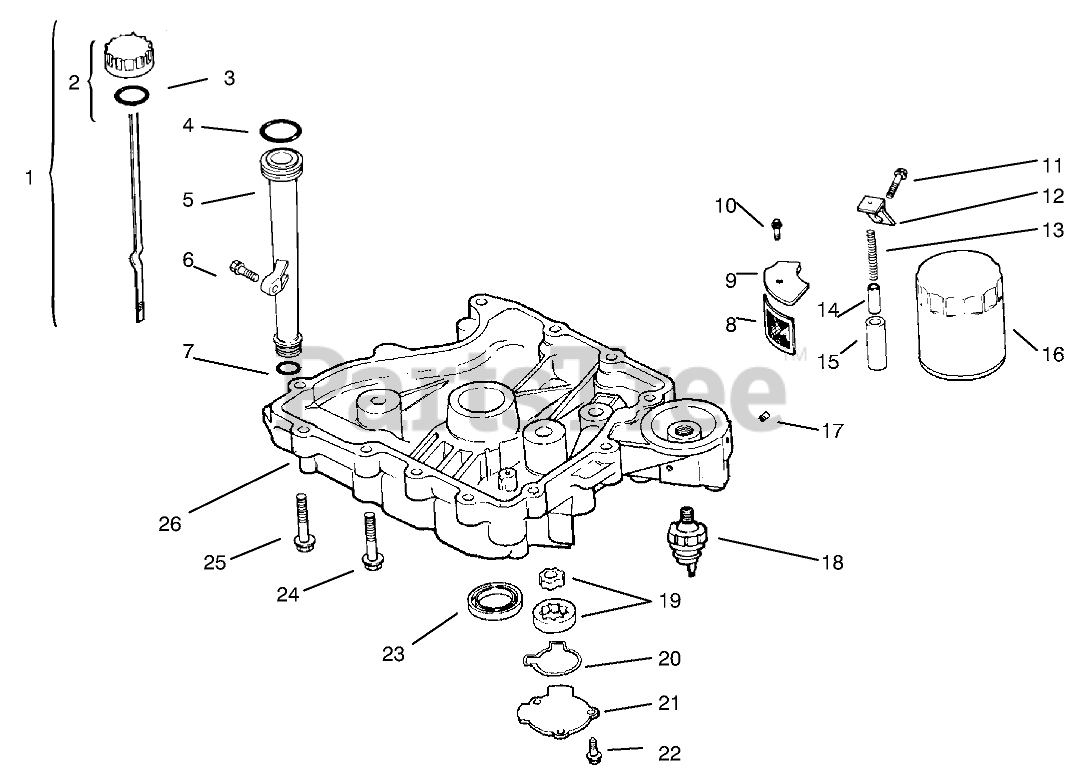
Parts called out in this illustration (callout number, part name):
1	Dipstick INC 2-3 (Only On: 92003, 92043)
2	Kit-Oil Cap INC 3 (Only On: 92003, 92043)
3	O Ring-Fill Cap (Only On: 92003, 92043)
4	O Ring-Upper Fill Tube (Only On: 92003, 92043)
5	Tube-Oil Fill (Only On: 92003, 92043)
6	Screw M5x0.8x20 (Only On: 92003, 92043)
7	O Ring-Lower Fill Tube (Only On: 92003, 92043)
8	Screen-Oil Pickup (Only On: 92003, 92043)
9	Cover-Oil Pickup Screen (Only On: 92003, 92043)
10	Screw M5x0.8x16 (Only On: 92003, 92043)
11	Screw M10x1.5x25 (Only On: 92003, 92043)
12	Bracket-Oil Pump Relief (Only On: 92003, 92043)
13	Spring-Oil Relief Valve (Only On: 92003, 92043)
14	Piston-Oil Relief Valve (Only On: 92003, 92043)
15	Body-Oil Relief Valve (Only On: 92003, 92043)
16	Filter-Oil (Only On: 92003, 92043)
17	Plug-SH 3/8 NPTF (Only On: 92003, 92043)
18	Switch-Oil Pressure (Only On: 92003, 92043)
19	Pump-Oil (Only On: 92003, 92043)
20	O Ring-Oil Pump Cover (Only On: 92003, 92043)
21	Cover-Oil Pump (Only On: 92003, 92043)
22	Screw M5x0.8x16 (Only On: 92003, 92043)
23	Seal-Crankshaft (Only On: 92003, 92043)
24	Screw M8x1.25x45 (Only On: 92003, 92043)
25	Screw
26	Pan-Oil (Only On: 92003, 92043)
